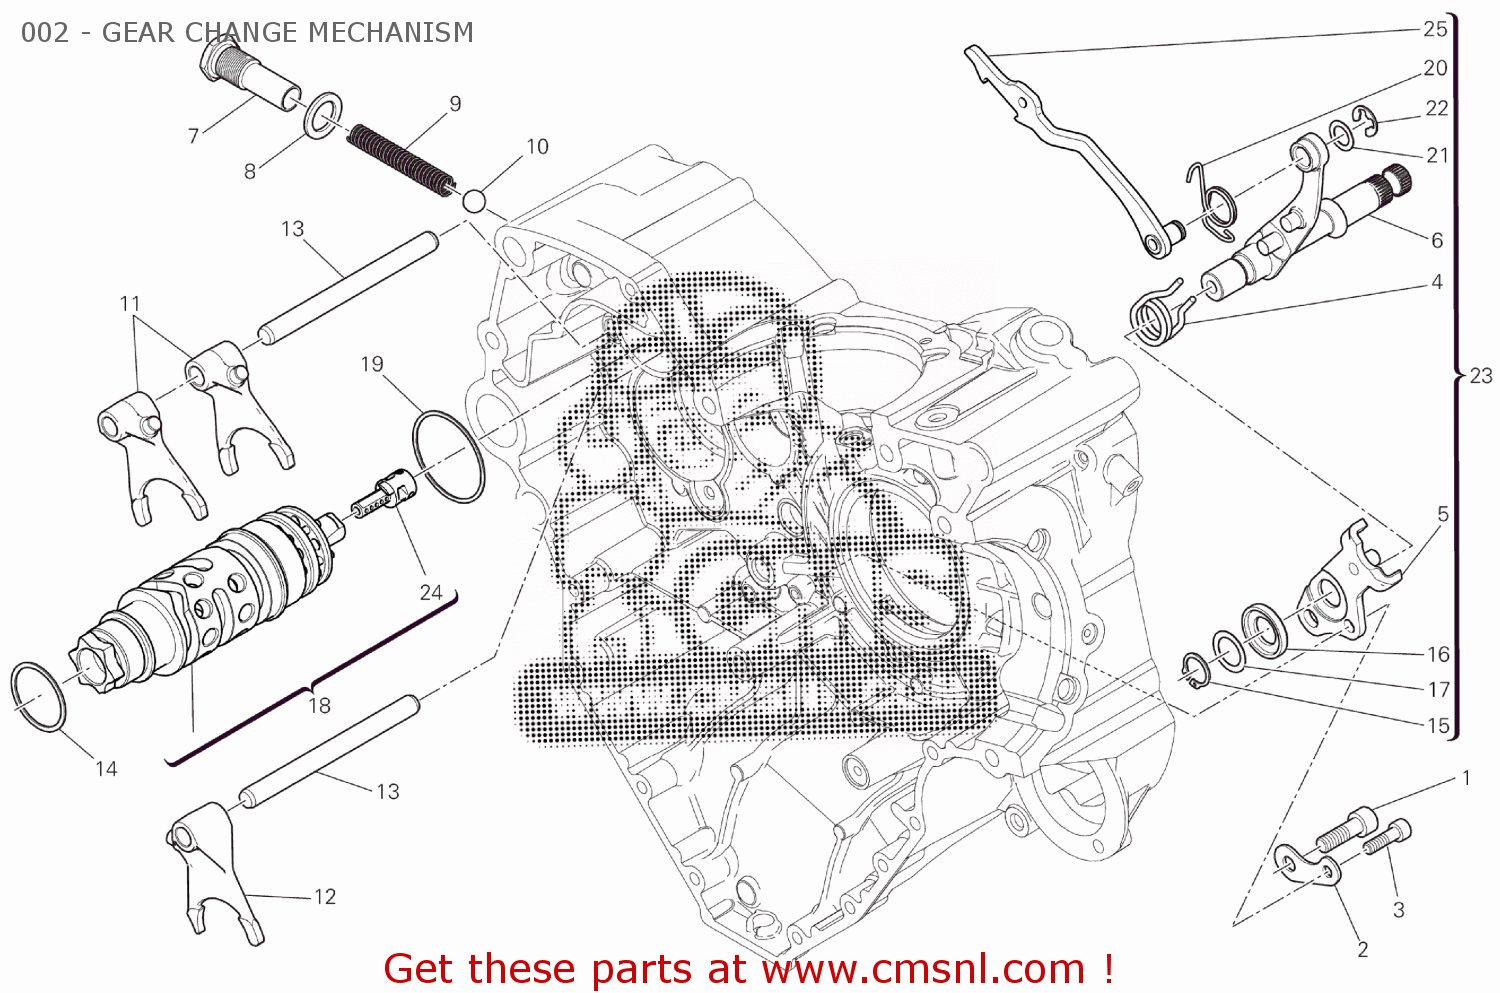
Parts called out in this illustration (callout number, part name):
1	SCREW
2	SPACER
3	SCREW
4	SPRING, SHIFT RETURN
5	STOPPER PLATE
6	GEAR SELECTOR SHAFT
7	SCREW M16X1.5
8	GASKET 16.2X24X2
9	GEAR SELECTOR SPRING
10	BALL 11MM
11	GEAR SELECTOR FORK,1ST/4TH-2ND/3RD
12	FORK-SHIFT, 5TH&6TH
13	FORK PIN
14	THRUST WASHER 1 MM
15	CIRCLIP 15 DIN 471
16	CENTERING RING
17	THRUST WASHER 15.5X22X0.5
18	COMPLETE GEARBOX DRUM
19	THRUST WASHER 45.2X49X0.9
20	RETURN SPRING
21	THRUST WASHER 10.5X16X0.5
22	SPRING RING
23	CONTROL FORK
24	MAGNETE
25	CONTROL FORK
